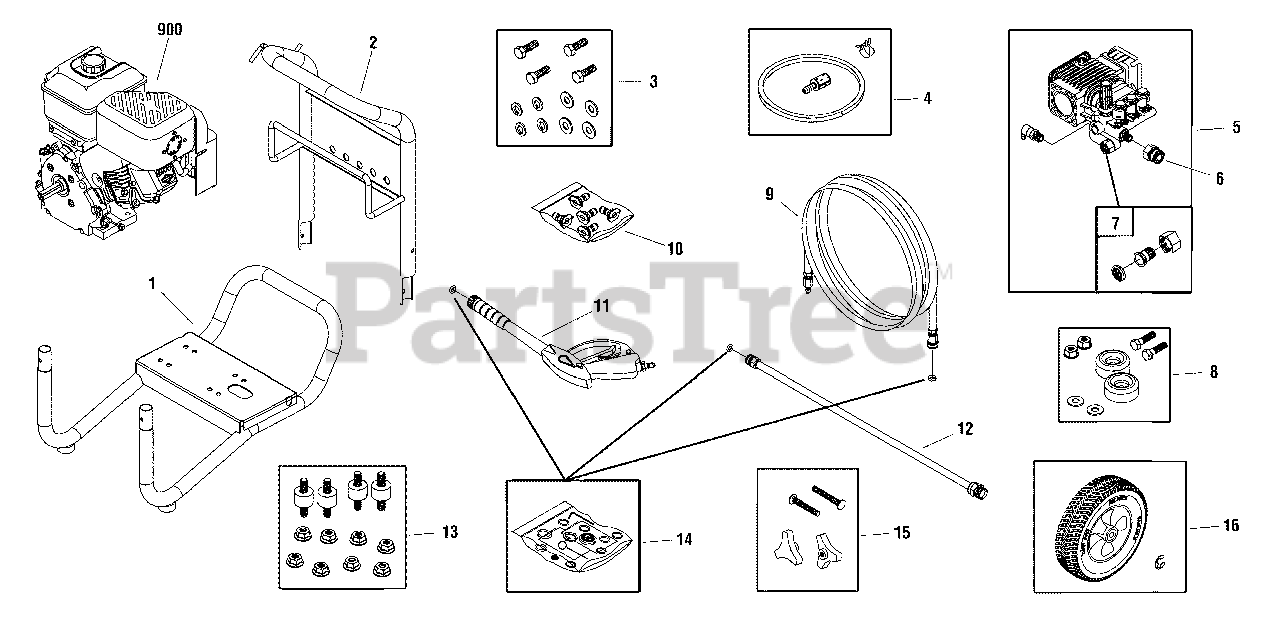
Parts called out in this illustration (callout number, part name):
3	* KIT, Hardware Pump Mounting
6	FITTING
7	ADAPTER, Garden Hose
8	* KIT, Vibration Mount
11	GUN
12	EXTENSION, QC
13	* KIT, Vibration Mount
14	* KIT, O-Rings
15	* KIT, Hardware Handle
900	ENGINE
